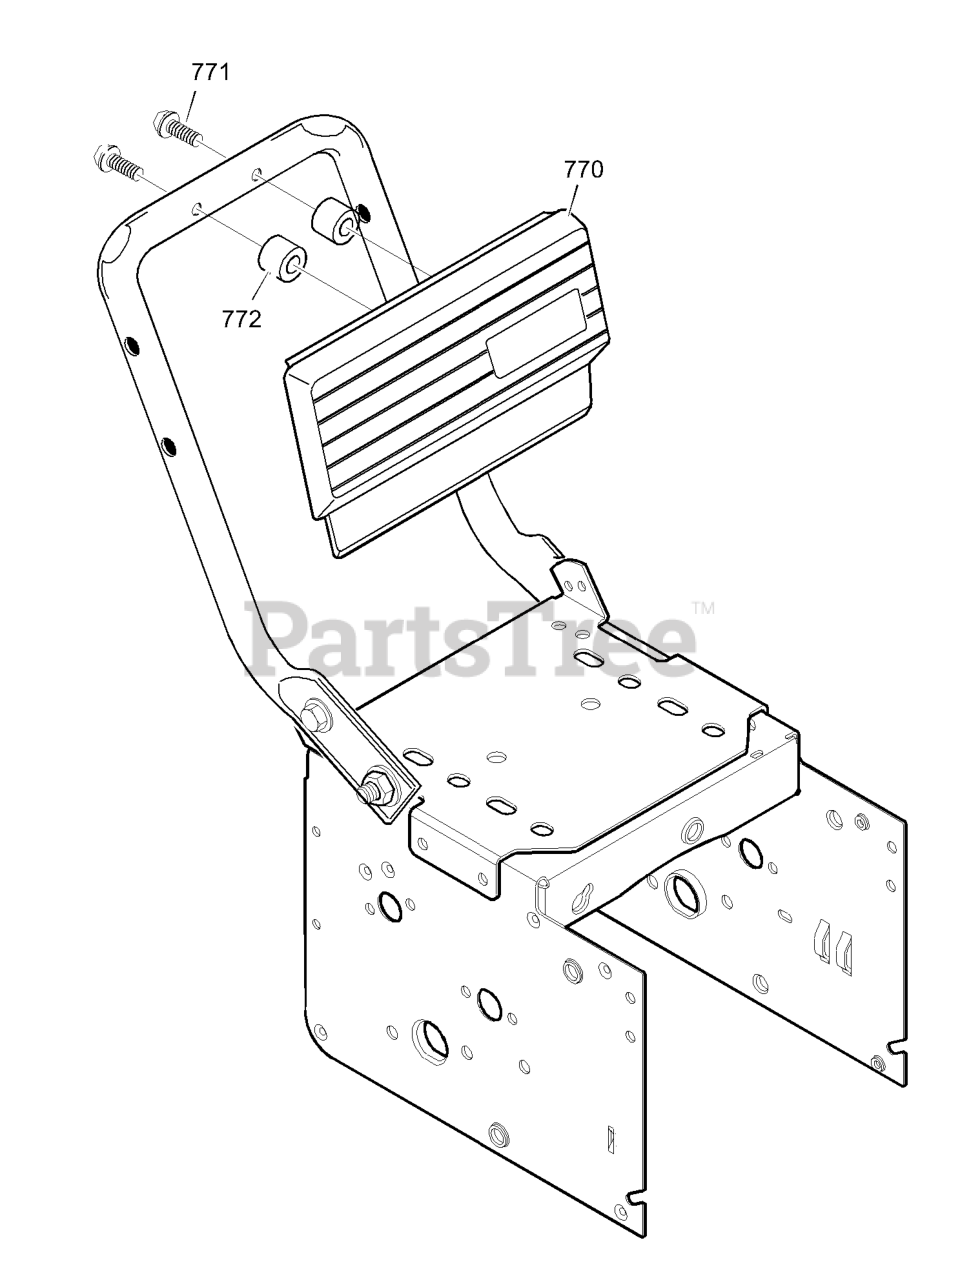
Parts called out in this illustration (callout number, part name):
770	PANEL, DECO -BLACK
771	SCREW, #10 -12 x 1.50
772	SPACER, SLEEVE
